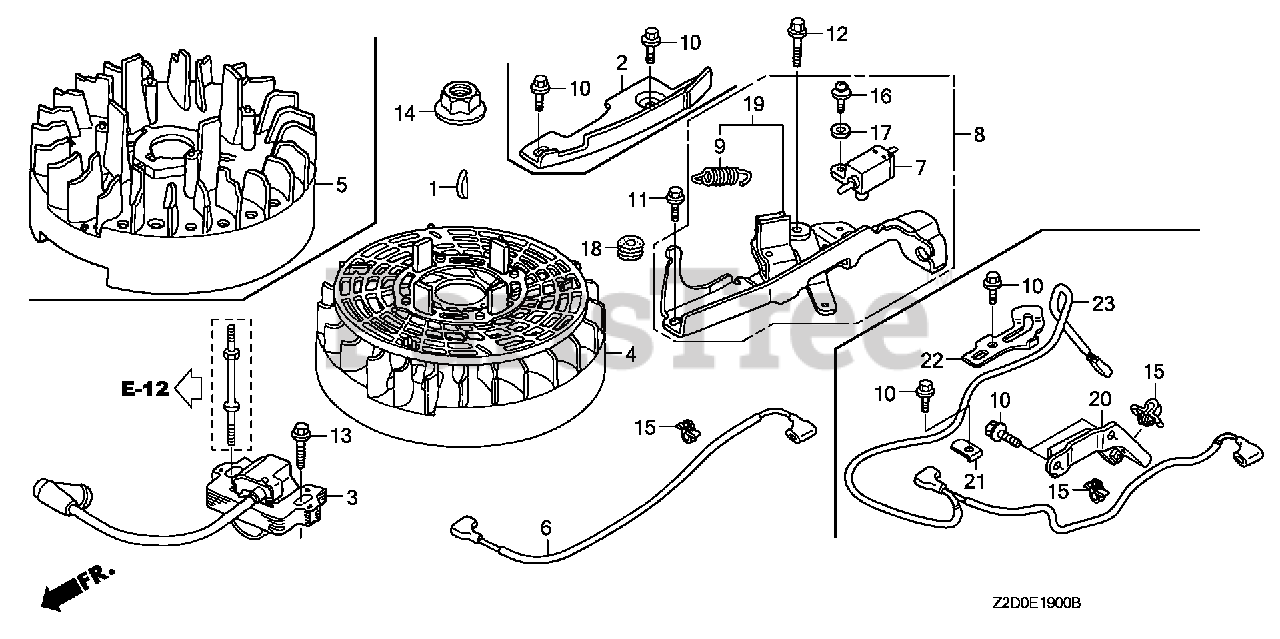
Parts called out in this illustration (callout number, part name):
1	KEY, SPECIAL WOODRUFF (25X18)
3	COIL ASSY., IGNITION (PHELON) (USE FOR F/W OF PHELON)
3	COIL ASSY., IGNITION (PHELON)
4	FLYWHEEL ASSY. (PHELON) (USE FOR IGN. COIL OF PHELON)
6	WIRE, STOP SWITCH
7	SWITCH ASSY., ENGINE STOP (N.C)
8	BRAKE ASSY.
9	SPRING, BRAKE LEVER
11	BOLT, FLANGE (6X14) (CT200)
12	BOLT, FLANGE (6X23) (CT200)
13	BOLT, FLANGE (6X20) (CT200)
14	NUT, FLANGE (14MM)
15	CLIP A, CABLE (3.8MM BLACK) (NIFCO)
16	SCREW-WASHER (4X12)
17	WASHER, PLAIN (4MM)
